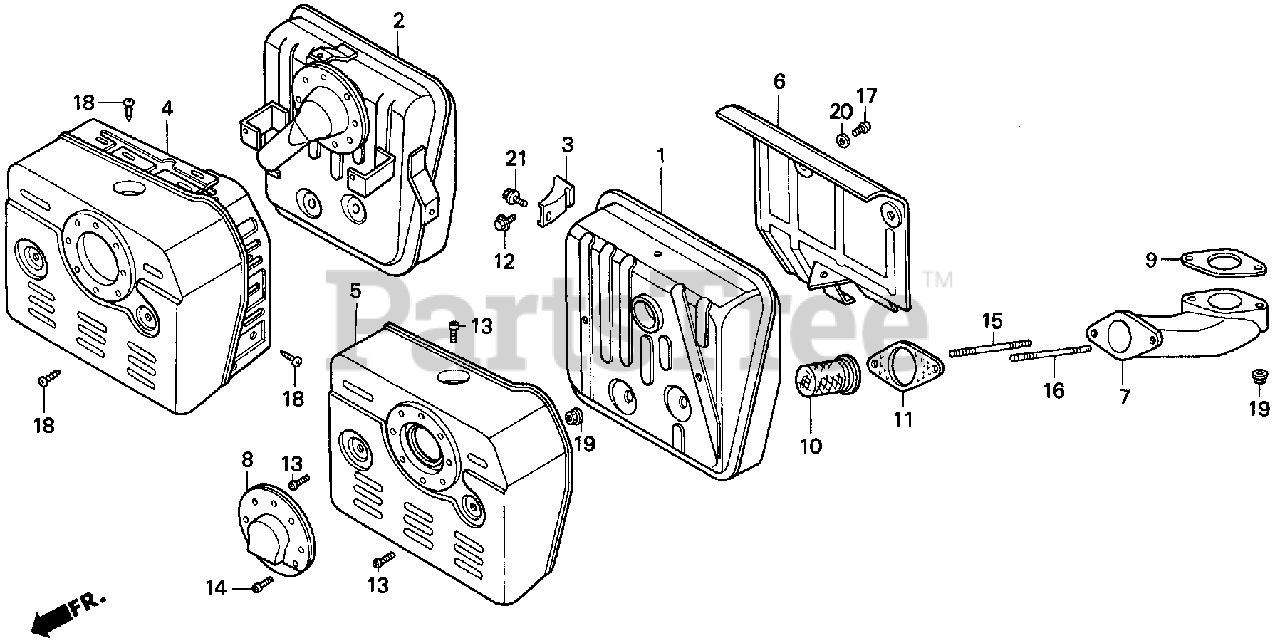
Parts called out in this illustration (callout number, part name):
1	MUFFLER
3	STAY, MUFFLER
5	PROTECTOR, MUFFLER
6	SEPARATOR, MUFFLER
7	PIPE, EX.
8	CAP, MUFFLER
9	GASKET, EX. PIPE (Honda Code 2108090). (NOT AVAILABLE)
9	GASKET, EX. PIPE
9	GASKET, EX. PIPE (WACKER)
11	GASKET, EX. PIPE (Honda Code 2278760). (NOT AVAILABLE)
11	GASKET, EX. PIPE
12	BOLT, FLANGE (8X16)
13	SCREW, TAPPING (5X8)
14	SCREW, TAPPING (4X6)
15	BOLT, STUD (8X60)
16	BOLT, STUD (8X70)
17	SCREW, PAN (6X6)
19	NUT, FLANGE (8MM)
20	WASHER, PLAIN (6MM)
21	BOLT, FLANGE (8X14)
